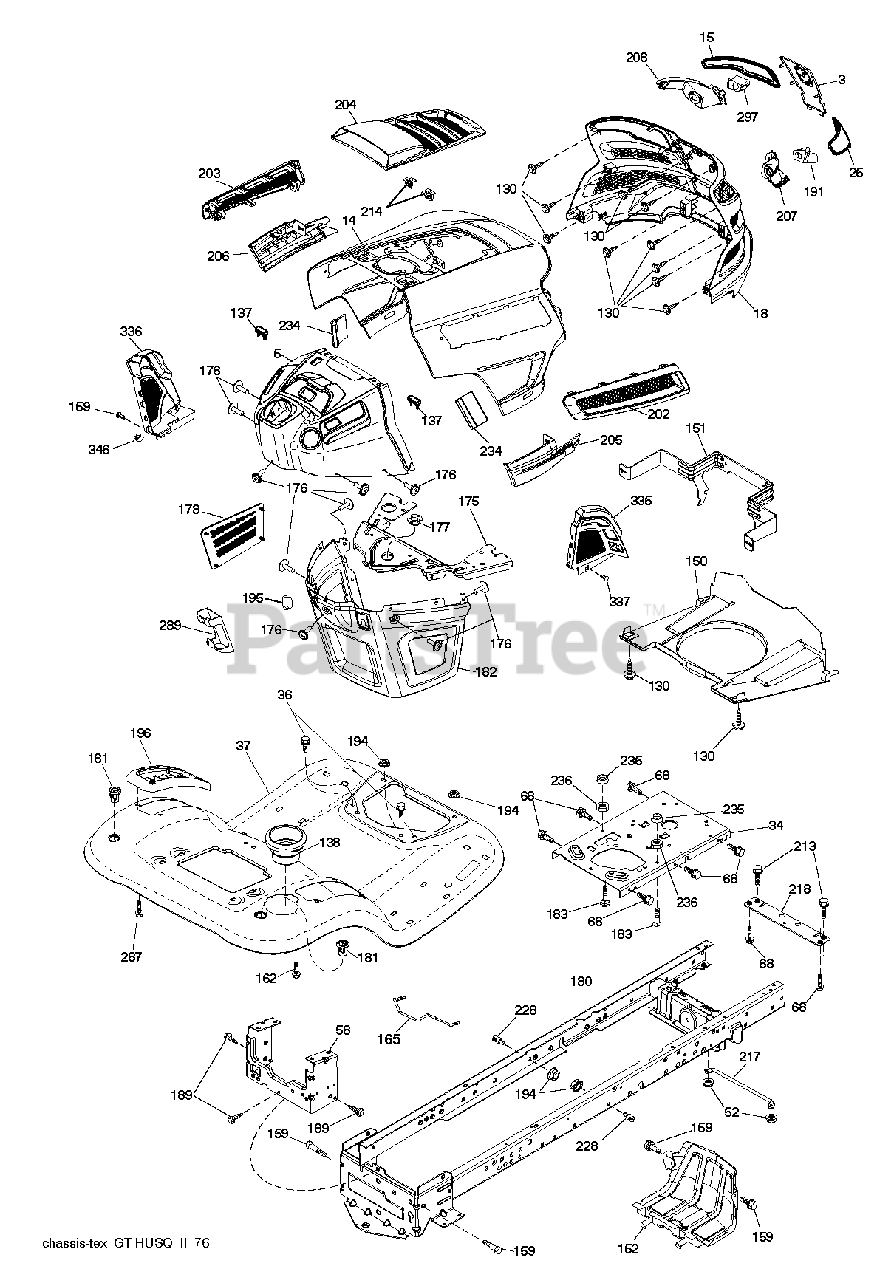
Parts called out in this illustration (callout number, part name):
3	APPLIQUE.SUBASM.GT.HUSQ.II
5	RP.DASH.UPP.GT2.SM.MC.CHOKE
14	HOOD.ASM.HUSQVARNA.GT.TEX.ORAN
15	LENS.HEADLIGHT.LH.GTII.2011
18	GRILLE.SUBASM.GT.HUSQ.II
25	LENS.HEADLIGHT.RH.GTII.2011
34	PLATE.ENGINE.WELDED.CHASSIS
36	SCREW 5/16"
37	FENDER.TLT.FS.W/CUPHLD.ORANGE
52	LOCKNUT
58	DRAWBAR UPPER 2PC SMALL FENDER
68	SCREW LT
130	SCREW.#10 X 0.750.BOS
137	BUMPER DASH
138	HOLDER.CUP.LT.GREY
150	AIR DUCT.GTV2(1.66"RING HEIGHT
151	BRACKET.PIVOT.HOOD.GT.HUSQ.II
152	SHIELD.BROWNING.PNT.GT.V2
159	SCREW, 3/8-16X3/4
162	SCREW.HI-LO.CONSOLE
165	SUPPORT.TANK.REAR.W/TEX
175	PLATE.CROSSMEMBER.HUSQ
176	SCREW.#10-24X5/8.RN.QU
177	BUSHING, STEERING
178	CARGO.ASM.NET.TXGT.W/C
180	CHASS.WLDMNT.TL.12GA/2P.48/54
181	BUSHING.MNT.FEND.CRGO.
182	DASH.LOWER.COMMON.12V.ADAPTOR
183	BOLT.5/16-18X1-1/4 FULL THD
189	SCREW
191	INSERT.REFLECTIVE.RH.HUSQ.GTII
194	NUT LOCK HEX FLANGE 5/16-18
195	PLUG.HOLE.DASH.LOWER.12V.BLK
196	DECKLFT.CONSOL FULL ASSM GREY
202	VENT.SIDE.RH.GT.HUSQ.II.
203	VENT.SIDE.LH.GT.HUSQ.II.498
204	VENT.TOP.HUSQ.GT2
205	SIDE.TRIM.RH.GT.HUSQ.II
206	SIDE.TRIM.LH.GT.HUSQ.II.GRAY
207	BEZEL LIGHT.RH.GT.II.MYLAR
208	BEZEL LIGHT.LH.GT.II.MYLAR
213	BOLT
214	CLIP.RETAINER.TINNER.
217	ROD.PIVOT.HOOD
218	X-PIECE.HOOD.STOP.NON/
228	STUD.FASTNER.W/ANTI-ROTATE
234	BUMPER.HOOD.TEX.HUSQVARNA
235	SPACER FENDER
236	NUT.CENTERLOCK.5/16-
287	SCREW 1/4X20
289	PLUG.N/CRUISE.COMMON.YT/GT.BLK
297	INSERT.REFLECTIVE.LH.HUSQ.GTII
335	COVER.RH.CLOSE.OUT.BLACK
336	COVER-LH.LOWER.DASH.GT2.BLACK
337	CLIP.XMAS.TREE.ITW.2622-00
346	CLIP,INSULATOR
